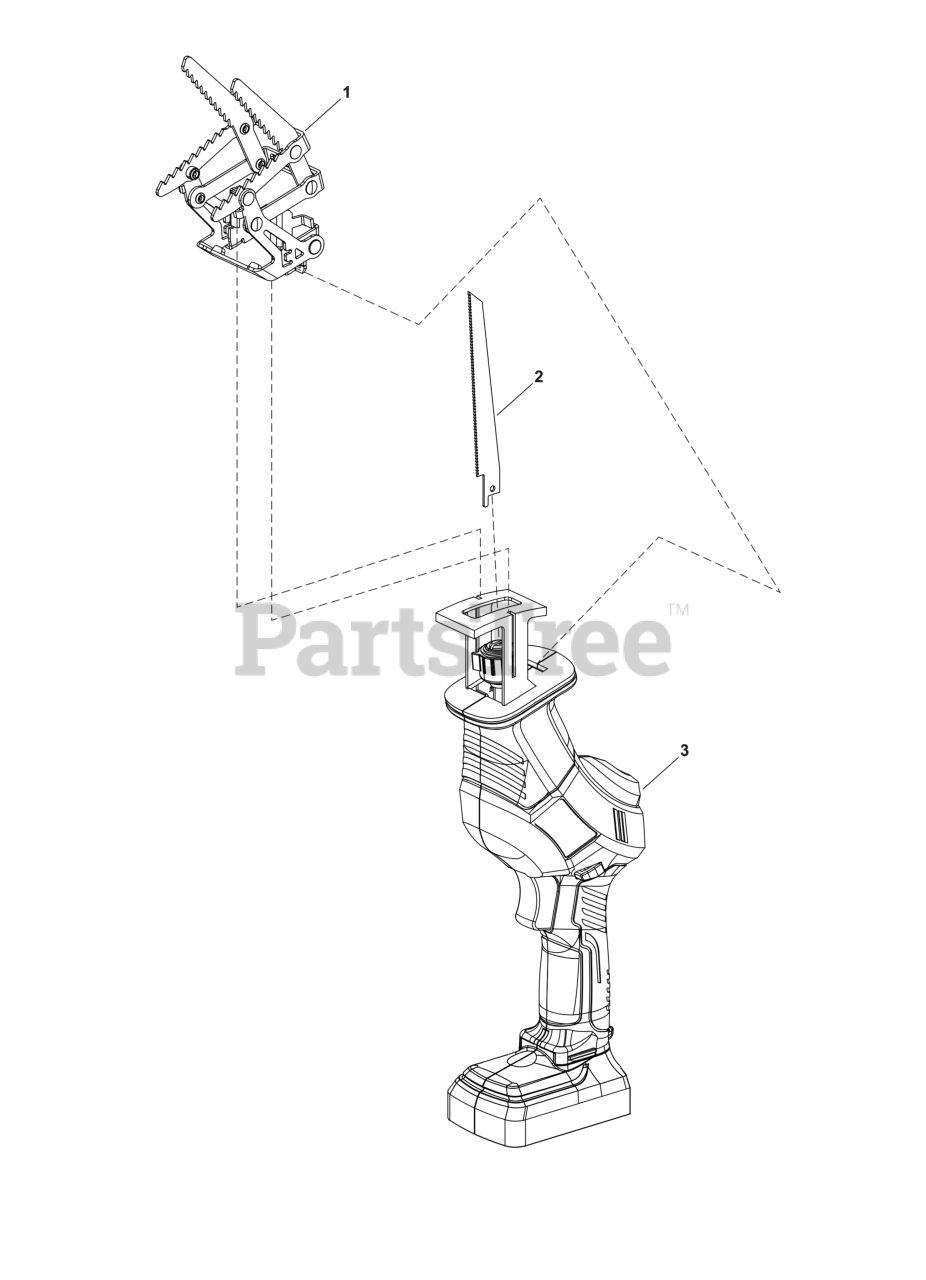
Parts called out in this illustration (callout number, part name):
1	CLAMPING JAW
2	SAW BLADE
3	MAIN BODY ASSEMBLY
